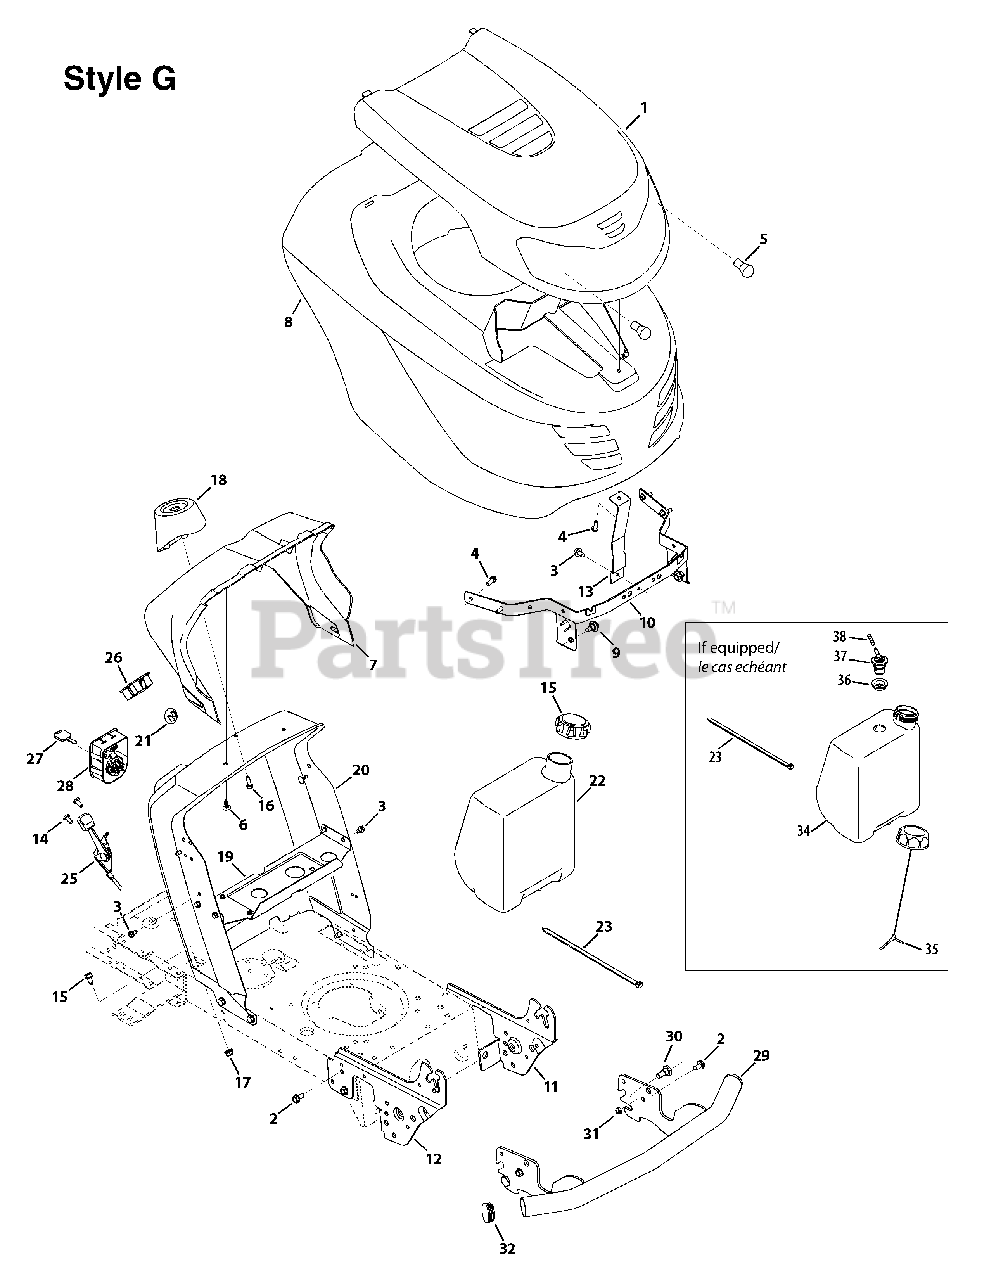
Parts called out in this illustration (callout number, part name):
1	Grille Style G Ass'y (incl. lens)
2	S-Tapp Screw 5/16-18 x .75
3	Hex Wash S-Tapp Screw 1/4-20 x .50
4	Hex Tapp Screw 1/4 x .75" Lg.
5	Miniature Lamp 12V Socket Type
6	Rachet Clip
7	Dash Collar
8	Hood Style G
9	Shoulder Screw 5/16-18, .43 x .29
13	Hood Support Bracket
14	Hex Wash Hd Screw. 1/4-20 x .500
15	Cap-Fuel
16	Hex Tapp Screw 1/4 x .75" Lg.
17	Flange Locknut 5/16-18 Gr. F, Nylon
18	Steering Support
19	Gas Tank Support Bracket
21	Choke Plug
22	Fuel Tank 1.5 gal.
23	Cable Tie
25	Choke/Throttle Cable
26	Indicator Monitor
28	Key Switch Module
30	Shoulder Screw. .498 x .340: 3/8-16
31	Hex L-Nut 3/8-16 Gr. B
34	Tank Ass'y 1.36 Gal.
35	Cap-Fuel
36	Rubber Grommet
37	Roll over Valve
38	Hose Vent
